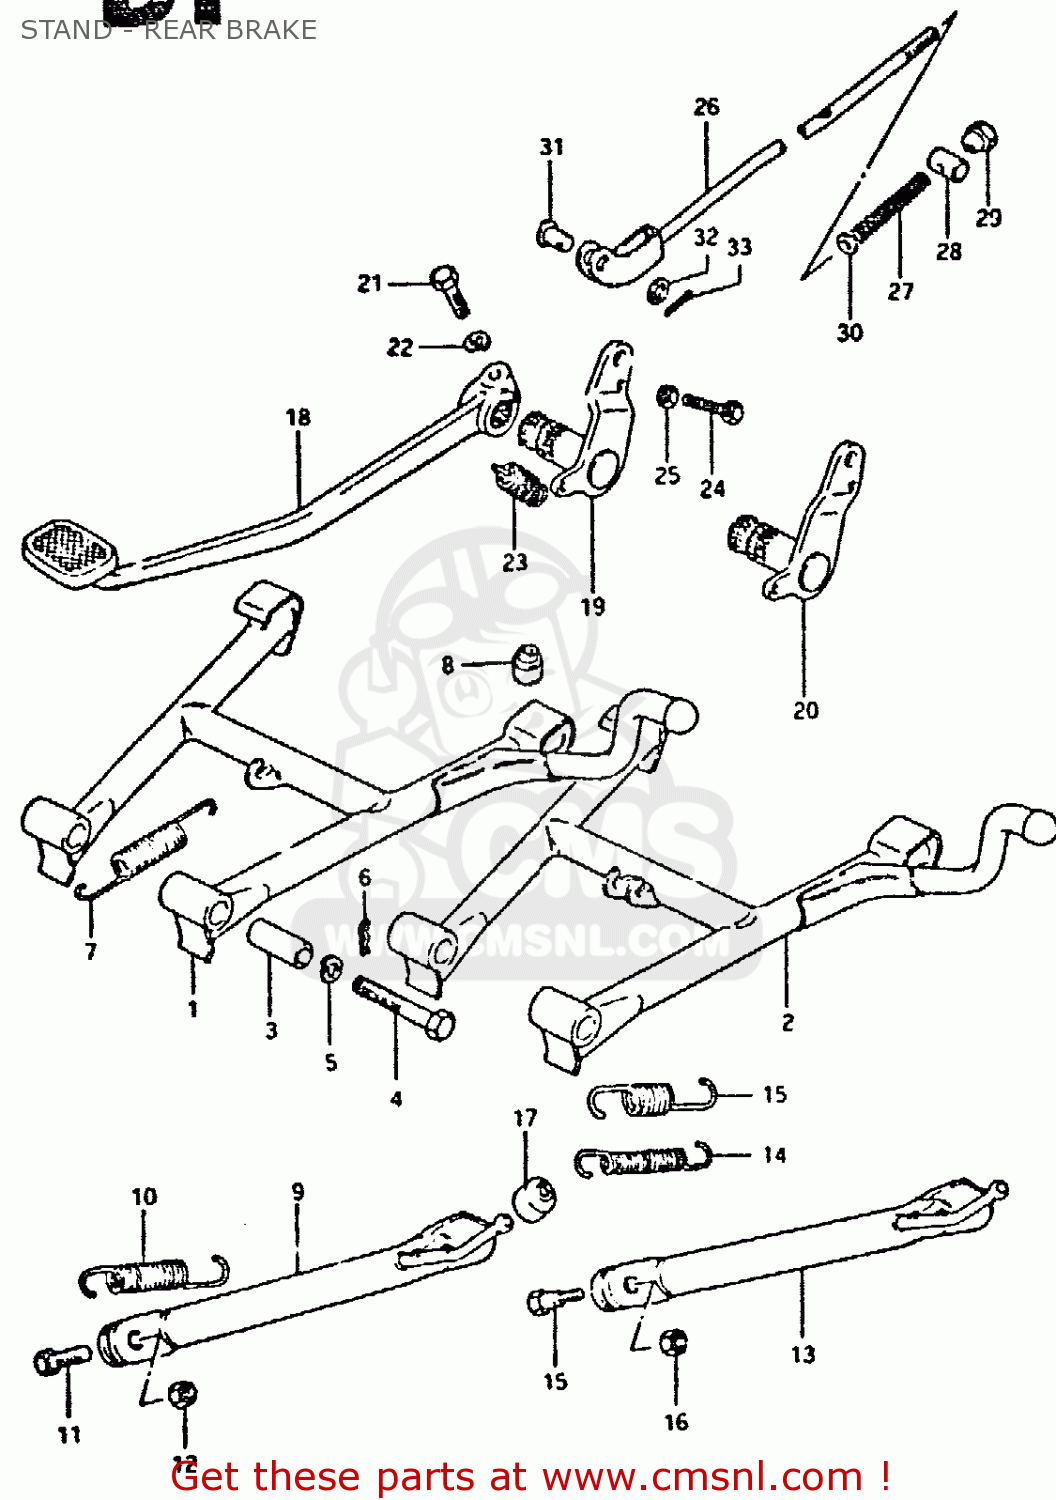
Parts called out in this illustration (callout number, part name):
1	STAND,CENTER
3	SPACER(10X16X38.8)
4	BOLT
5	LOCK WASHER
6	CLIP
7	SPRING
8	CUSHION
9	STAND,SIDE
10	SPRING
11	BOLT(10X30)
12	NUT
17	CUSHION
18	PEDAL,BRAKE
19	ARM,BRAKE PEDAL ROD
21	BOLT
22	LOCK WASHER
23	SPRING
24	BOLT
25	NUT
26	ROD ASSEMBLY,REAR BRAKE
27	SPRING
28	PIN
29	NUT
30	WASHER
31	PIN(L:13.5)
32	WASHER
33	PIN 20X20
